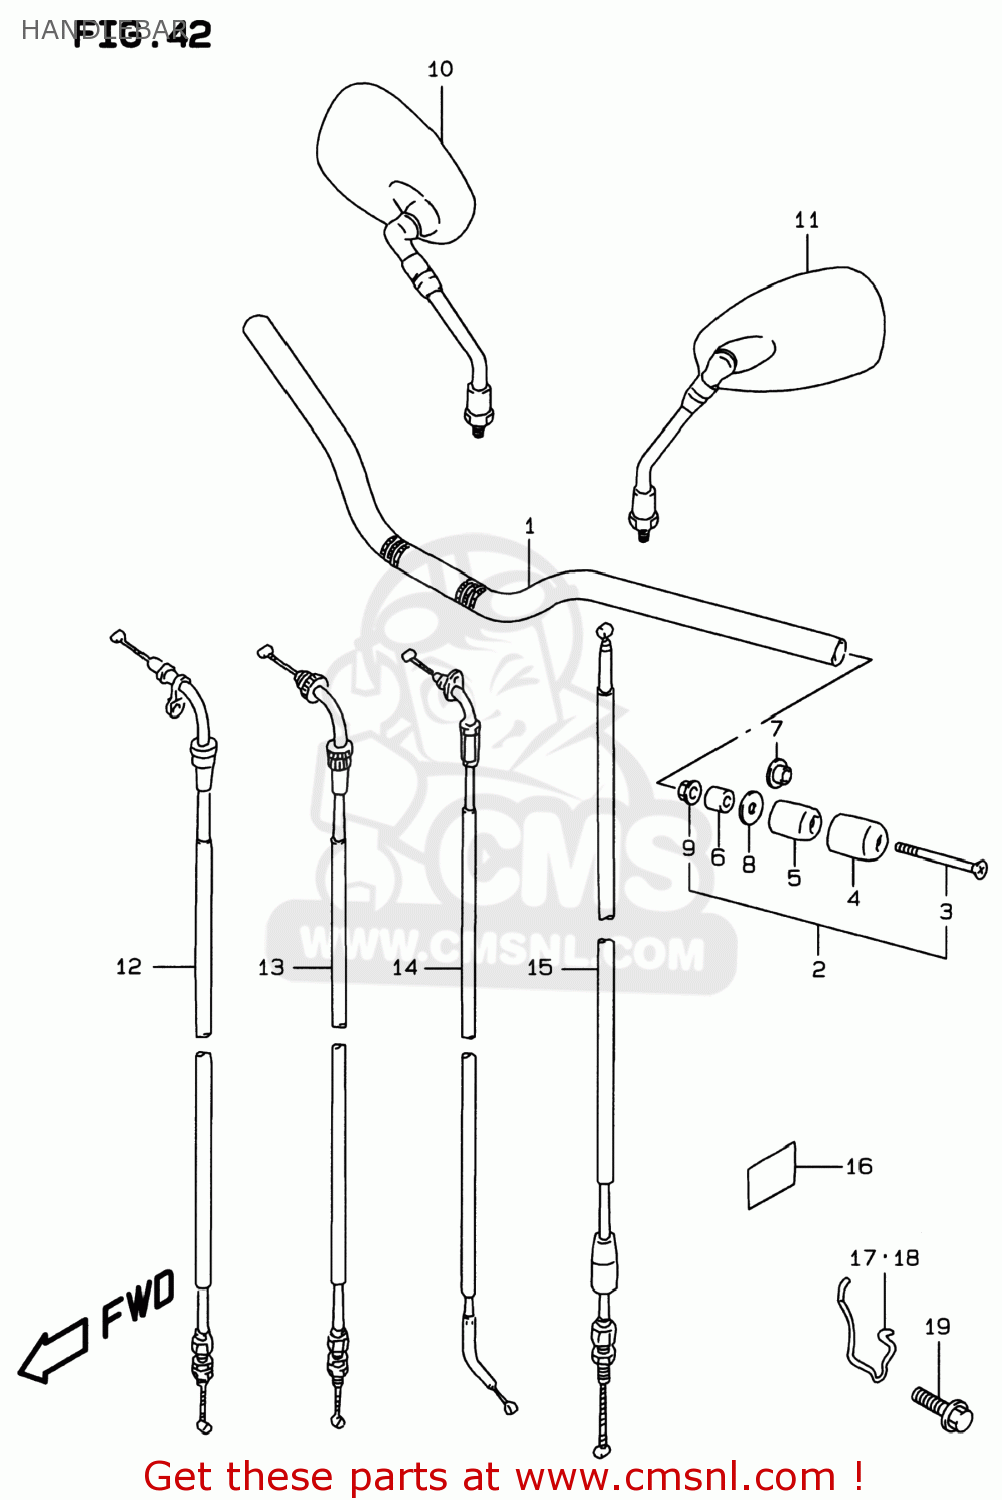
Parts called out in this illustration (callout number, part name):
1	HANDLEBAR
2	BALANCER SET,HANDLEBAR
3	SCREW
4	CAP,BALANCER
5	BALANCER,HANDLE
6	SPACER,BALANCER
7	NUT
8	EXPANDER,HANDLE BALANCER
9	NUT
10	MIRROR ASSEMBLY,REAR VIEW
11	MIRROR ASSEMBLY,REAR VIEW
12	CABLE ASSY,THROTTLE NO.1
13	CABLE ASSY,THROTTLE NO.2
14	CABLE COMP,STARTER
15	CABLE ASSY,CLUTCH
16	PROTECTOR,FRAME COVER FR
17	GUIDE,CABLE NO.1
18	GUIDE,CABLE NO.2
19	BOLT
